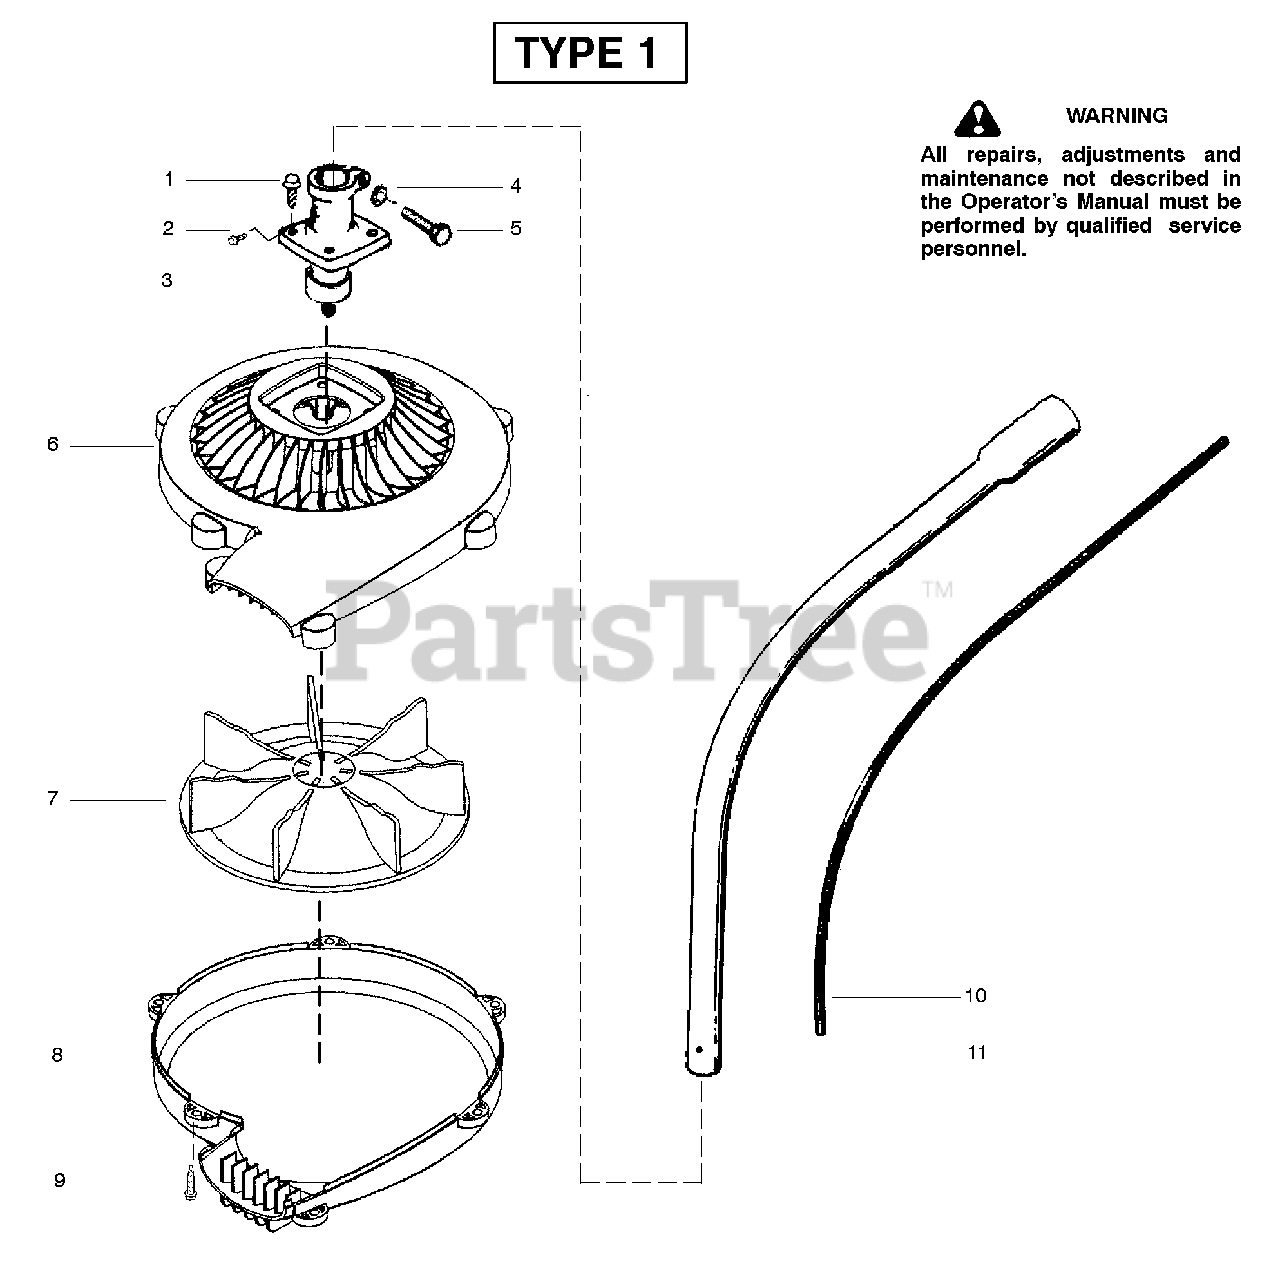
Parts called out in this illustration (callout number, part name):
1	Screw (brg hsg/blwr)
2	Screw-Shaft Alignment
3	Assy-Bearing Hsg.
4	Washer-Lock (star)
6	Blower-Scroll (upper)
7	Impeller
8	Blower-Scroll (lower)
10	Flexshaft-Split Boom
11	Assy-Lower Driveshaft
